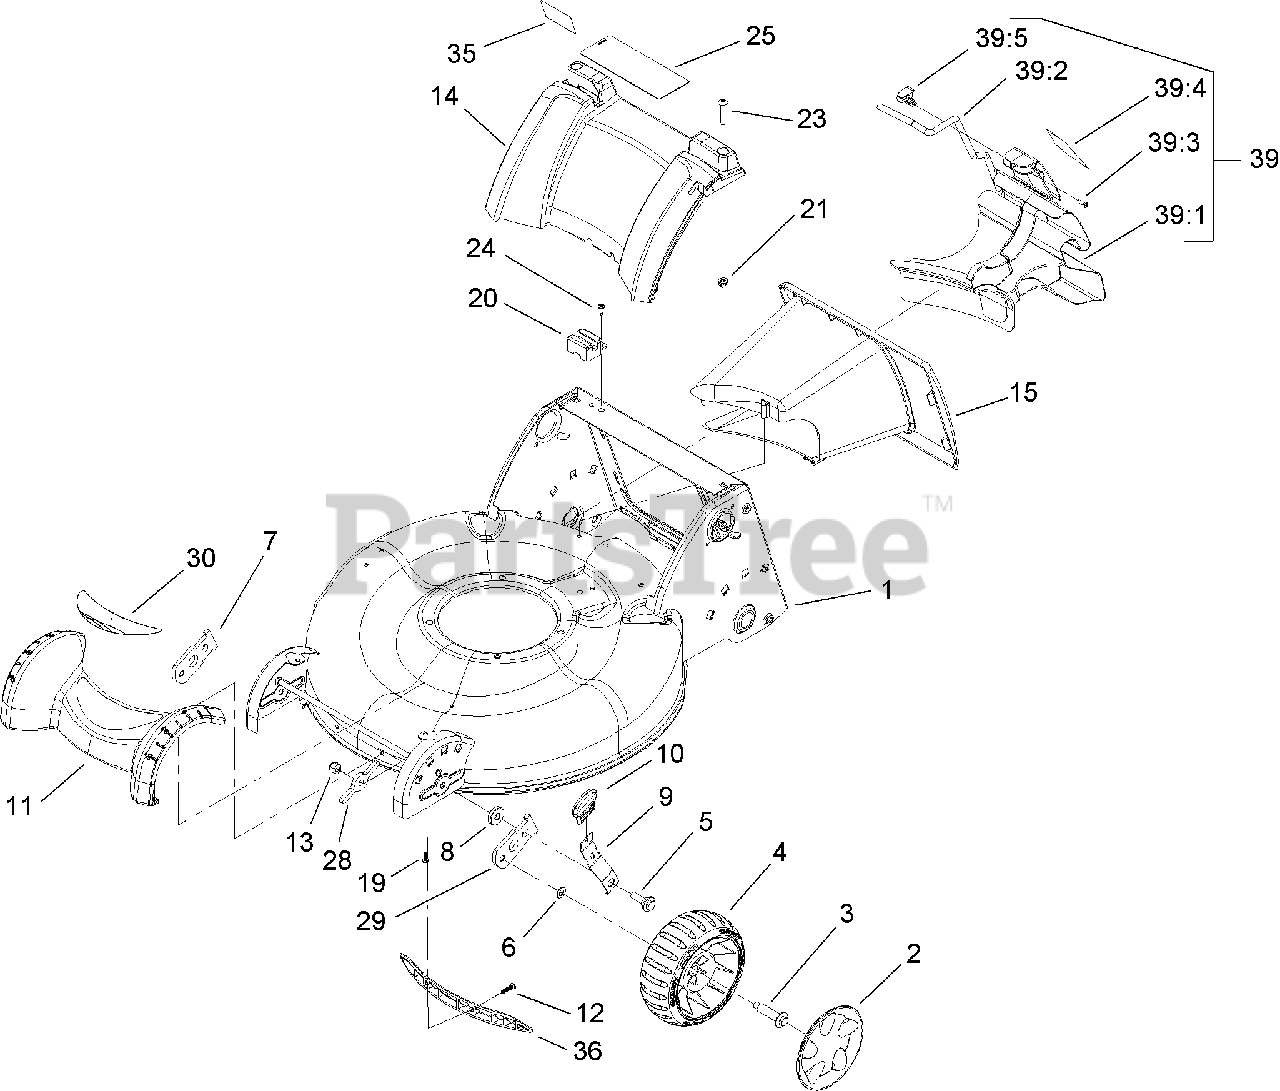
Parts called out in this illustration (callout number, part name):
1	HOUSING ASM
2	COVER-WHEEL, 7 INCH
3	BOLT-SHOULDER
4	7 INCH WHEEL ASM
5	BOLT-SHOULDER
7	ARM-PIVOT, RH
9	ARM-SPRING
10	KNOB-LEVER, HOC
11	COVER-FRONT
12	SCREW-PLASTITE
13	NUT-LOCK, NI
14	COVER-REAR
15	TUNNEL
19	SCREW-PLASTITE
20	MODULE-SWITCH
21	NUT-CLIP
23	SCREW-PTH
24	SCREW-THREAD FORMING
25	DECAL-WARNING
28	WASHER-SUPPORT, FRONT
29	ARM-PIVOT, LH
35	DECAL-BAG ATTACHMENT, CE
36	INSERT-HOUSING
39	MULCH PLUG ASM
39:1	PLUG-CHUTE
39:2	LATCH-PLUG
39:3	SCREW-PPH
39:4	DECAL-MULCH PLUG, CE
39:5	RETAINER-LATCH
